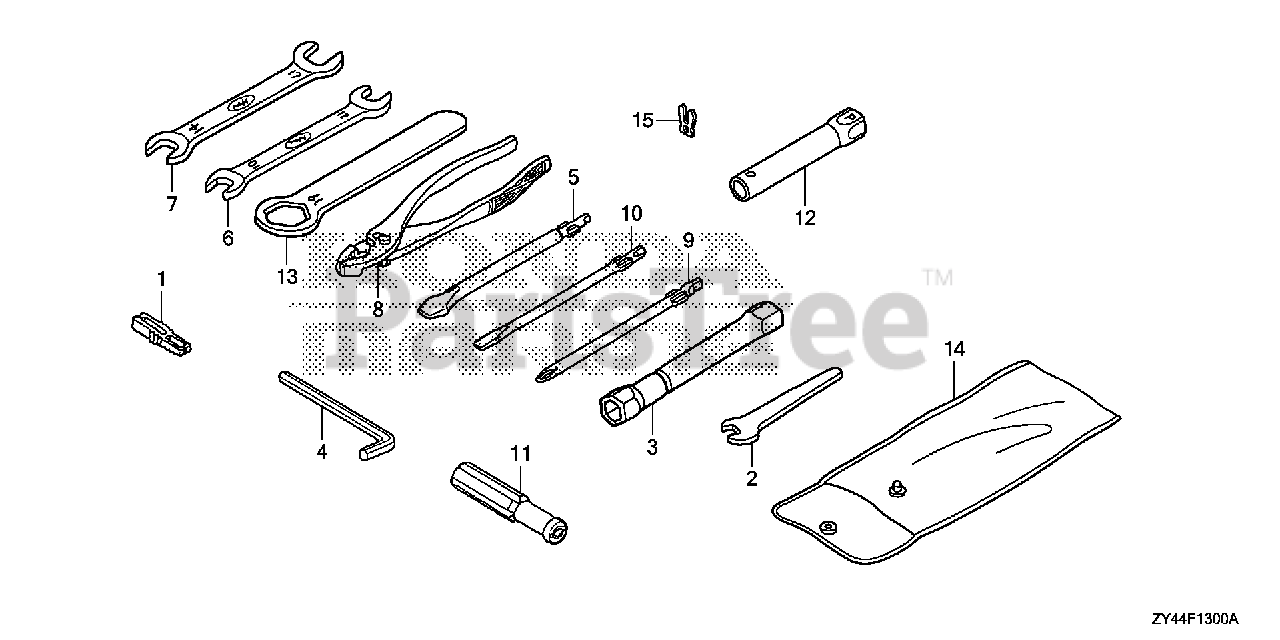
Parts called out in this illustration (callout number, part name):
1	PULLER, MINI FUSE (SUMITOMO)
2	SPANNER (8MM) (NOT AVAILABLE)
3	WRENCH, PLUG
4	WRENCH, HEX. (6MM)
5	SCREWDRIVER, CHECK BOLT
6	SPANNER (10X12)
7	SPANNER (14X17)
8	PLIERS (135) (KOWA)
8	PLIERS (135)
9	DRIVER 1, PLUS SCREW (NO.2)
10	DRIVER 3, MINUS SCREW (NO.2)
11	GRIP, SCREW DRIVER
12	WRENCH, BOX (P16X17)
13	WRENCH, EYE (19MM)
15	CLIP, EMERGENCY LOCK
